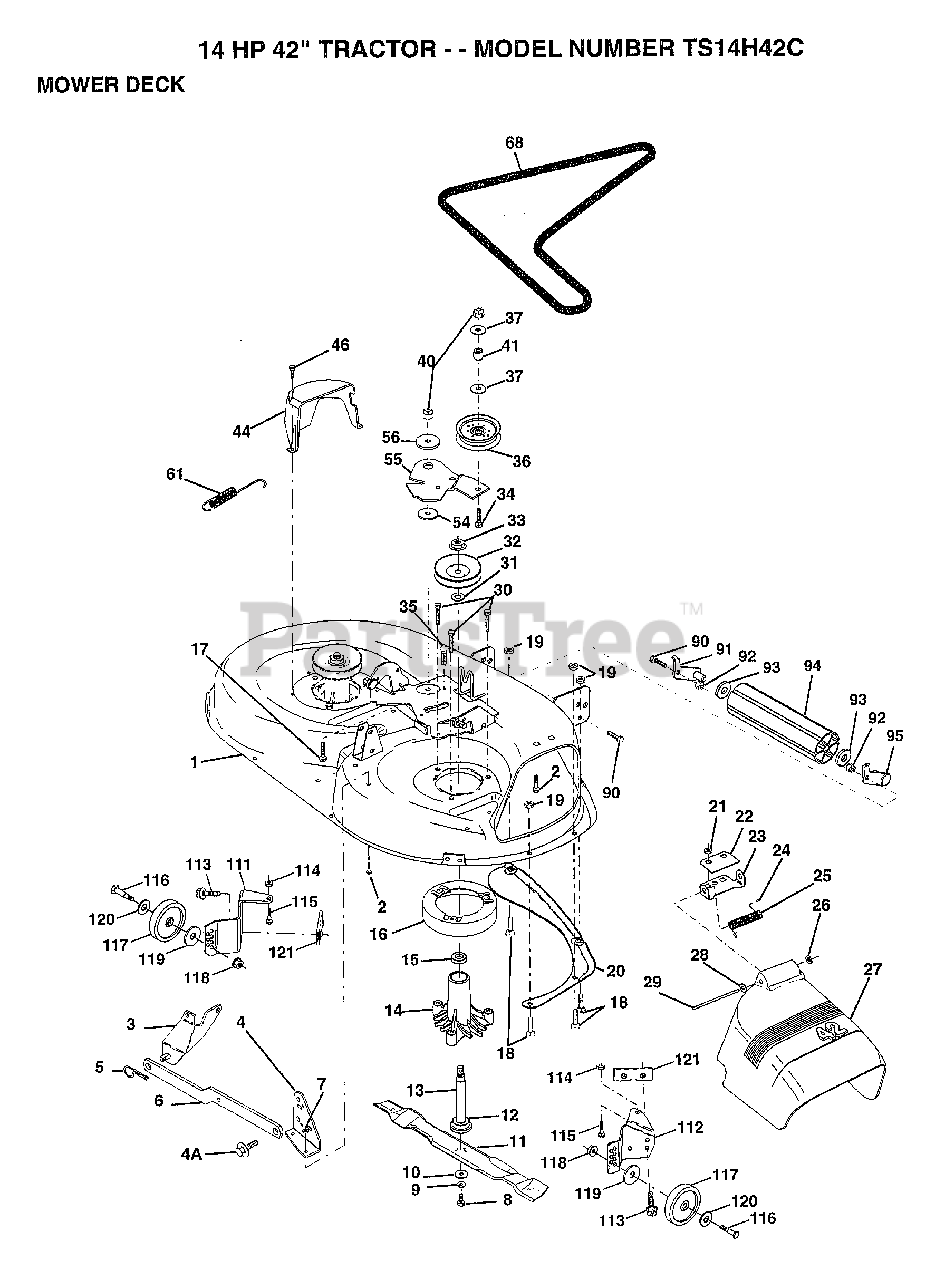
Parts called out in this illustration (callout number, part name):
2	BOLT
3	BRKT ASM SWAY BAR
4	BRKT DECK SW BAR
4A	BOLT SHD 5/16-18
7	NUT
8	BLADE BOLT
10	WASHER.HARD.BLADE
11	"BLADE.42"" MULCHER"
12	BEARING.BALL
14	HSG ASM MANDREL
15	BEARING
16	STRIPPER RND MWR
17	BOLT RDHD 3/8-16
18	BOLT
19	NUT
21	NUT
22	STIFFENER BRKT
23	DEFLECTOR BRKT
24	CAP-SLEEVE LT
25	SPRING TORSION
26	NUT PUSH M
27	DEFLECTOR.SHIELD
28	WASHER
29	HINGE ROD
31	WASHER
34	BOLT
35	XMAS TREE FASTNER
36	FLAT IDLER PULLEY
37	WASHER
40	NUT
44	GUARD MAND LH BLK
46	SCREW.1/4-20X5/8
54	HARDENED WASHER
56	SPACER RETAINER
61	SPRING.EXTENSION
68	BELT-V MWR 82.625
90	BOLT
92	NUT
93	WASHER
113	SCREW
116	BOLT M
117	WHEEL.GAGE.BLK.PL
118	LOCKNUT
119	WASHER
120	WASHER
121	BRACKET.EXTRD.GWL
